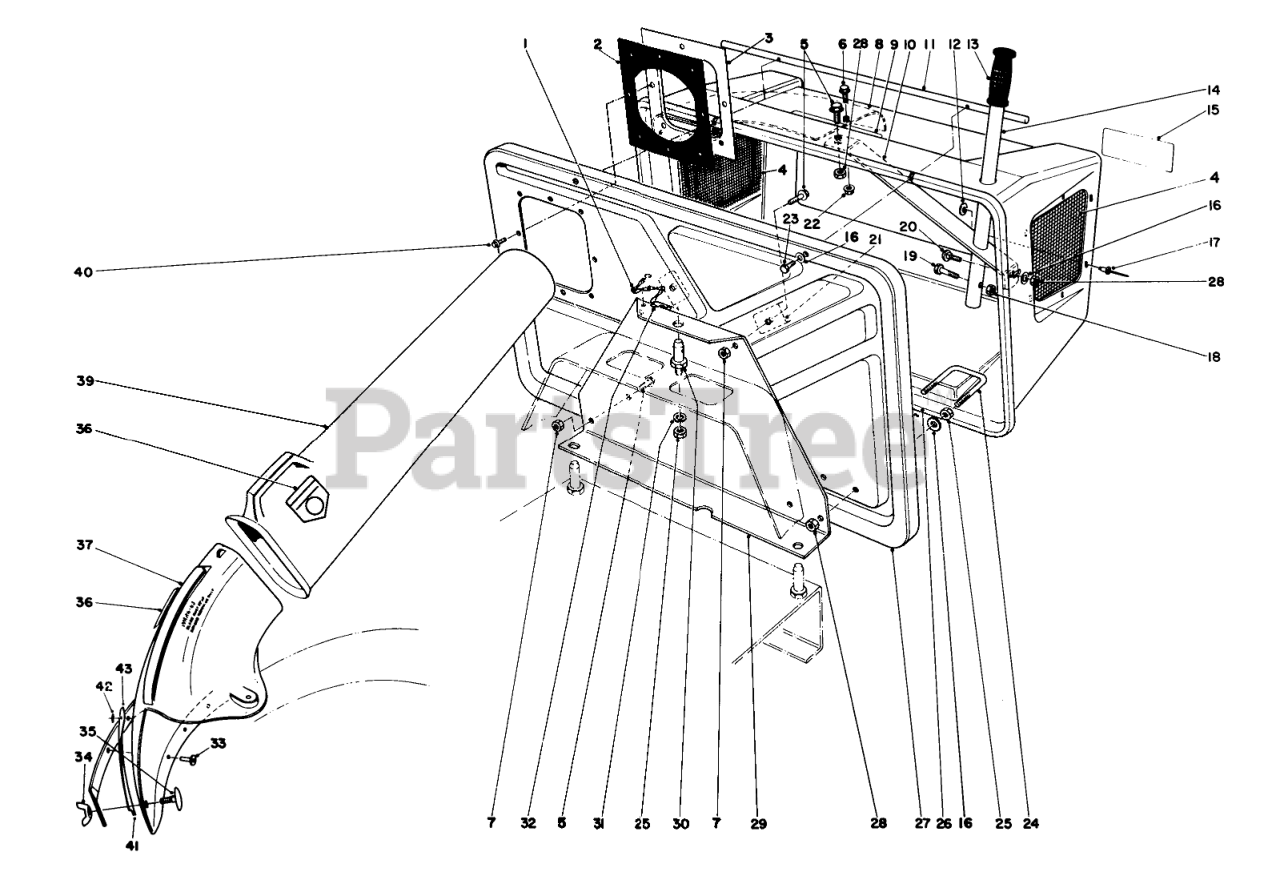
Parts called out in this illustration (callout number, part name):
1	6-LINK CHAIN W/HOOK
2	INLET SEAL
3	FRAME SEAL
4	SCREEN
5	SCREW-HHF
6	SCREW-HWH
7	NUT-HEX, SIDE DEFORM
8	DEFLECTOR
9	DECAL
10	HANDLE GUIDE
11	PIVOT ROD
12	WASHER-FLAT
14	HANDLE TUBE
15	EASY EMPTY BAG DECAL
16	WASHER-FLAT
17	RIVET-POP
18	NUT-HEX, SIDE DEFORM
19	SCREW-HH
20	BOLT-CARR
21	Retainer
22	NUT-LOCK, FLANGE
23	SCREW-HH
24	LATCH
25	NUT-HEX
26	HOPPER
28	NUT-LOCK, NI
29	Plate Mounting
30	Pin-Mounting
31	WASHER-LOCK
32	HAIRPIN COTTER
33	RIVET 3/16 X 7/16
34	NUT-WING
35	STEP BOLT
36	DECAL-DANGER
37	Chute Assembly (Incl. Ref. #33, 36 & 41-43)
39	Duct Assembly (Incl. Ref. #36)
40	SCREW
41	Shield
42	WASHER-PLAIN
43	Strap
